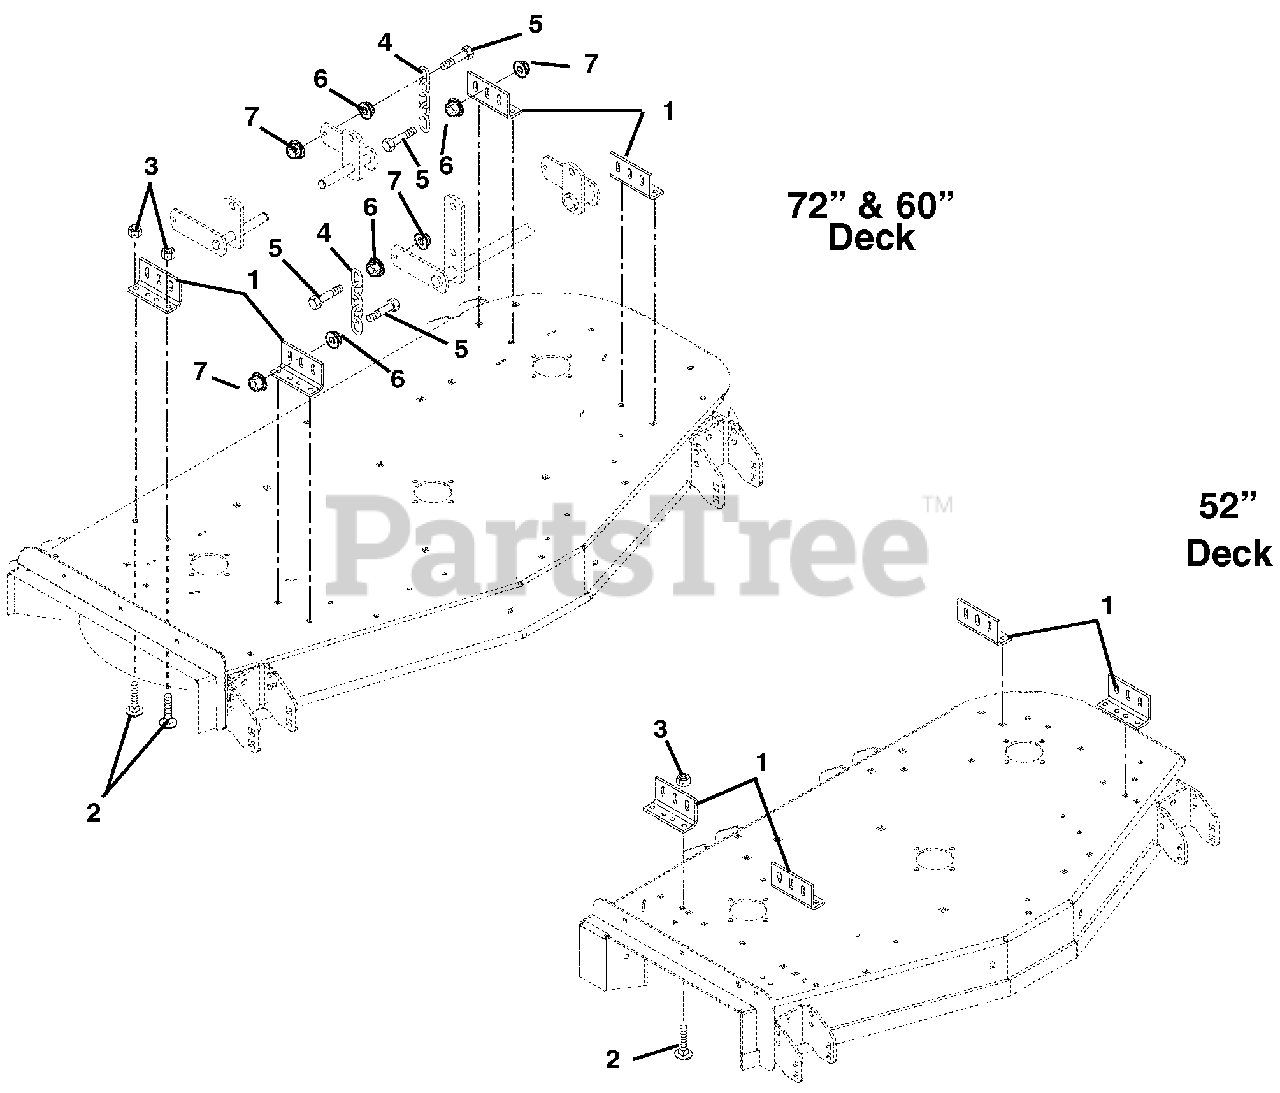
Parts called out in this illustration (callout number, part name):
1	Bracket, Mower Mounting
2	Bolt-Round Head Square Neck .38-16 x 1.00 Grade 2
3	Nut-Locking-Top-Flange .38-16
4	Chain, Link
5	Bolt-Hex .50-13 x 2.00 Grade 5
6	Nut, Spin Lock Flange .5-13
7	Nut-Locking-Top-Flange .50-13
